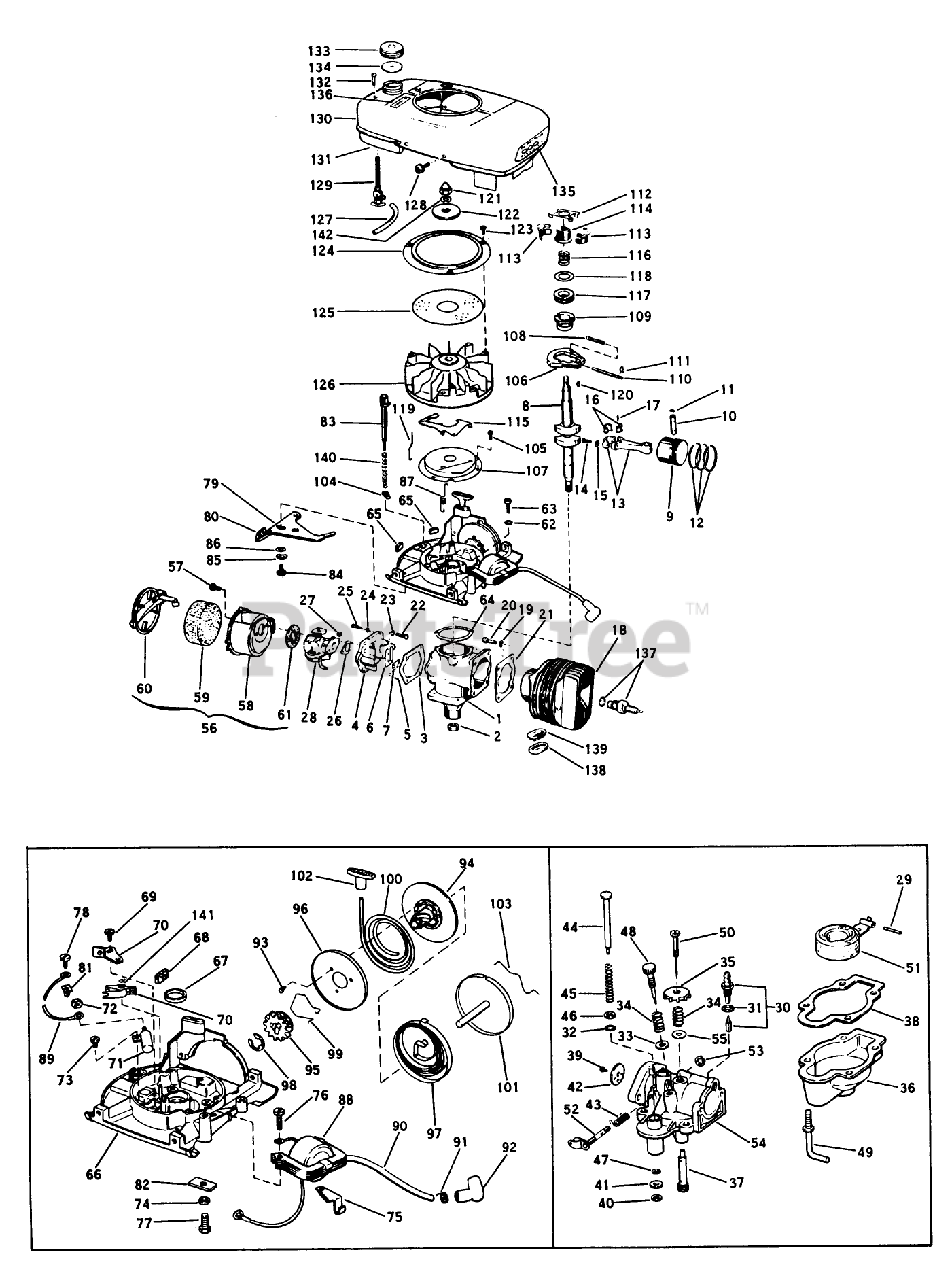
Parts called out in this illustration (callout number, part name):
7	PLATE-BACKUP, REED
11	RING-RETAINING
16	LINER ASM
21	GASKET S
25	SCREW S
26	GASKET S
27	STOP NUT
34	Spring-Ndl. Adj.
37	NOZZLE S
38	GASKET S
42	THROTTLE DISC S
44	DISC. SEE PRC4
48	Screw-Idle Adjustment
50	NEEDLE AY. S
52	THROTTLE LEVER S
53	RING GRIP S
57	SCREW S
59	AIR FIL.ELEM S
64	GASKET S
70	BREAKER AY. S
75	Clip-High Tension Wire
77	SCREW S
78	Screw Shut-off Switch
81	NUT - CLIP
90	LEAD AY. S
92	Cover-Rubber
95	STARTER PINION S
97	SPRING S
99	STARTER SPRING S
103	SPRING S
105	SCREW S
106	FLYWEIGHT S
107	DUST COVER S
108	SPARK ADV. SPRING S
109	SPARK ADV. S
110	PIN,SPARK ADV. S
111	SPARK ADJ. SPRING
114	COLLAR S
115	LEVER-GOVERNOR S
116	SPRING S
117	THRUST COLLAR S
124	Ring-Flywhl. Scrn.
128	SCREW S
129	VALVE&SCREEN SM
133	Gas Cap
135	Decal-Lawn Boy
136	Decal-Foot Pad
137	Spark Plug Gasket
138	GASKET S
140	SPRING S
